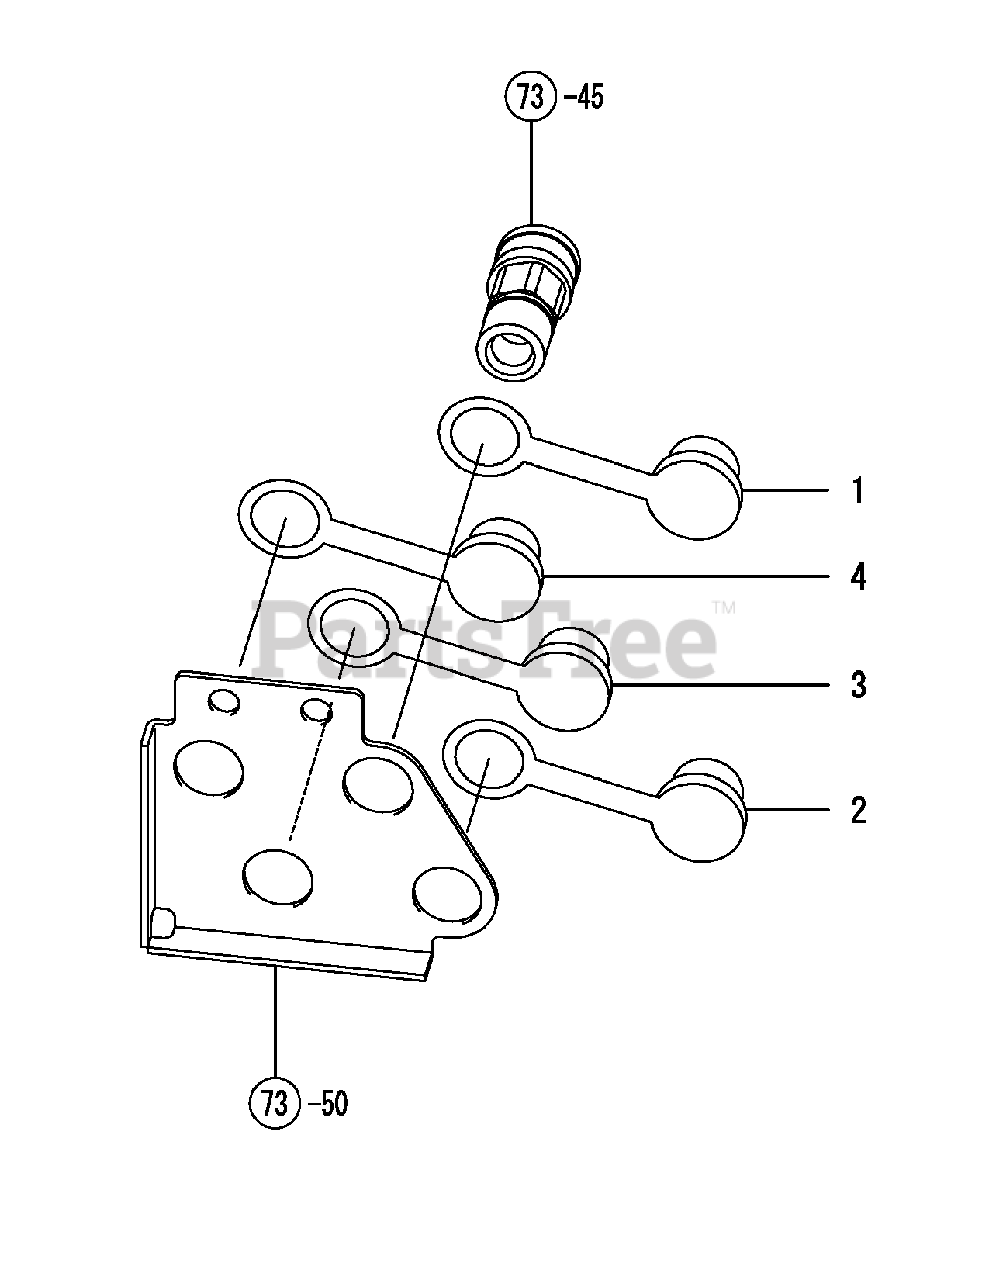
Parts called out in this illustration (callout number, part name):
1	Dust Plug 1/4( Red
2	Dust Plug 1/4( Blue
3	Dust Plug 1/4( Yel
4	Dust Plug 1/4( Gre
